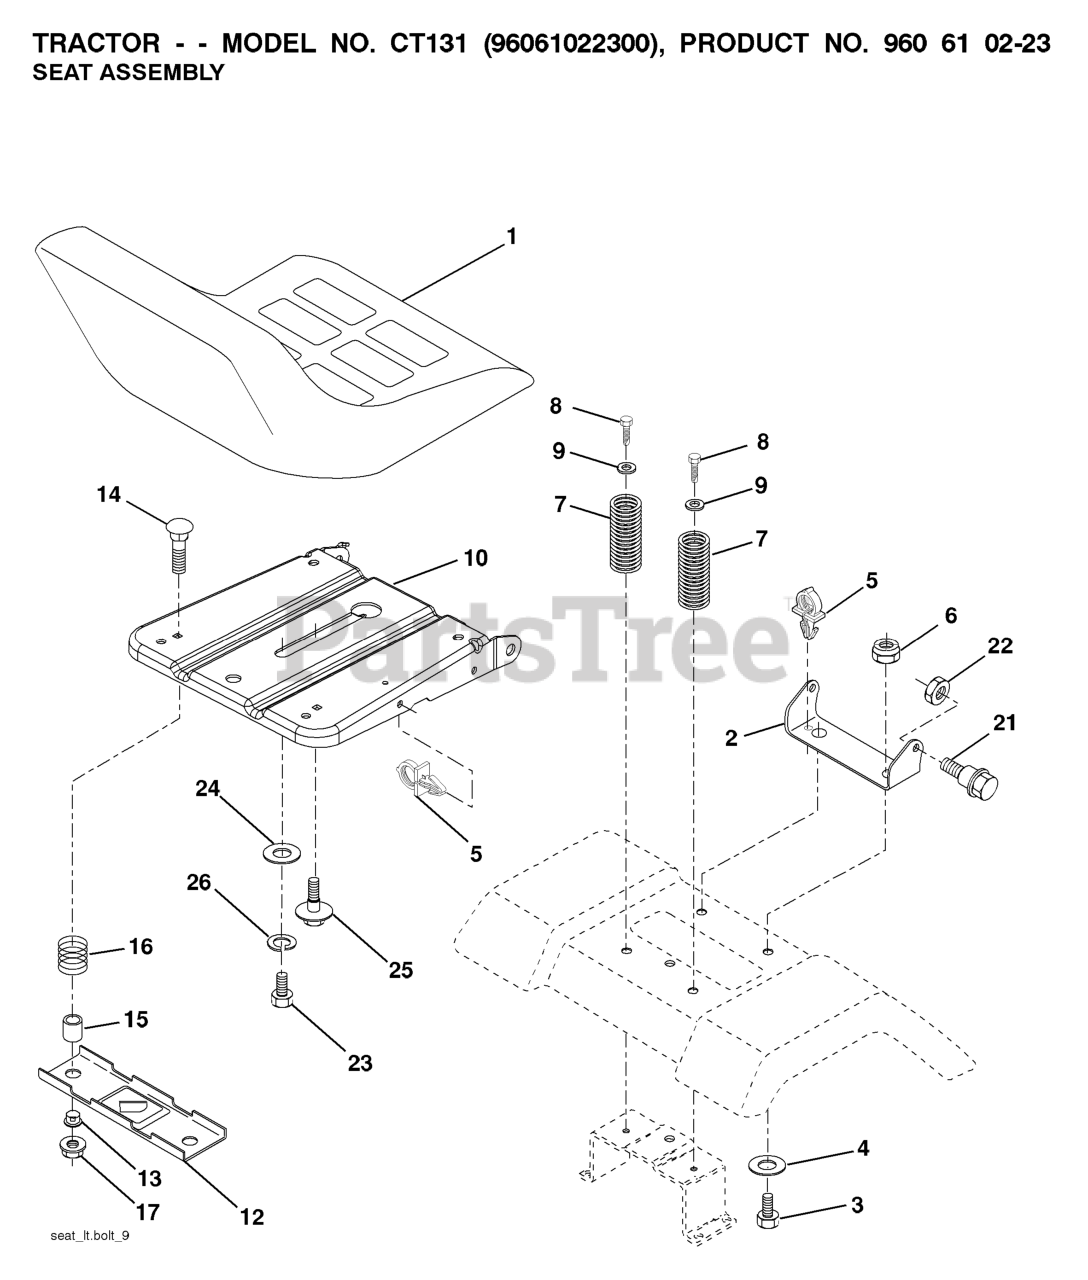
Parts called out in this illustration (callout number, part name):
1	SEAT.XG090.BLK.KB/BLT.NO-LOG
1	CONTROL.AW2.21FGD.
2	SEAT PIVOT BRKT
2	RP CASE.CONT.ROL.TOP.HUSQV.
3	BOLT, HEX 3/8-16X1
3	CAM.GEN2.DUAL.TRIGGER
4	LEVER.CONTROL.LH.22+.CURVE.BLA
5	SPRING, DRIVE CONTROL
6	NUT
6	BUSHING.CONTROL.CAM
7	SPRING COMPRESSION
7	COVER.DR.CONTROL.LOWER.GRAY
8	SCREW 3/8-16X1
8	LEVER.CONTROL.RH.22+.CURV.BLAC
9	WASHER
9	RP CABLE.CONTROL.21FGD.GEN2
10	PAN.ASM.SEAT.1SLOT
10	BRACKET.DRIVE.CONTR.GEN2.BLACK
11	WHEEL.8X1.75.H3SPK.RAD3.GY.BU3
12	BRKT.MNTNG.SWITCH.SEAT.BLACK
12	E-RING 7/16 RE
13	PINION.14.TEETH.FGD
14	BOLT.ROUND.HEAD.SQUARE.NECK
14	COVER.DUST.WHEEL
15	SPACER SPLIT 28X.96
15	PAWL, DRIVE
16	WASHER FLUT
17	NUT T
17	BEARING
18	SELECTOR KNOB
20	SCREW, PHILLIPS HEAD 10 X 5/8
21	BOLT.SHOULDER.5/16-18
22	NUT.71038.31-18.HEX.NYLOCK
23	BOLT.HEX.BLACK
25	BOLT,SHOULD
25	BELT KEEPER
26	LOCKWASHER
27	SCREW, HEX HD TAPPING #10-24 1
28	COVER.DRIVE.21.FWGD.GRAY
29	BELT.DRIVE.FG
32	RP PULLEY.DRIVE.EZ
33	NUT.HEX.FLANGE.3/8-16.LO(3 2)
35	RP KIT, WHEEL ADJUSTER, LH
36	TRANSMISSION.21.FGD.HT.VST
38	LOCKNUT.NYLOC.1/4-20
41	KIT, WHEEL ADJUSTER, RH
54	RB GBAG.33230247T.SIL.HUSQ.BLU
57	FRAME.GBAG.21.FWGD
